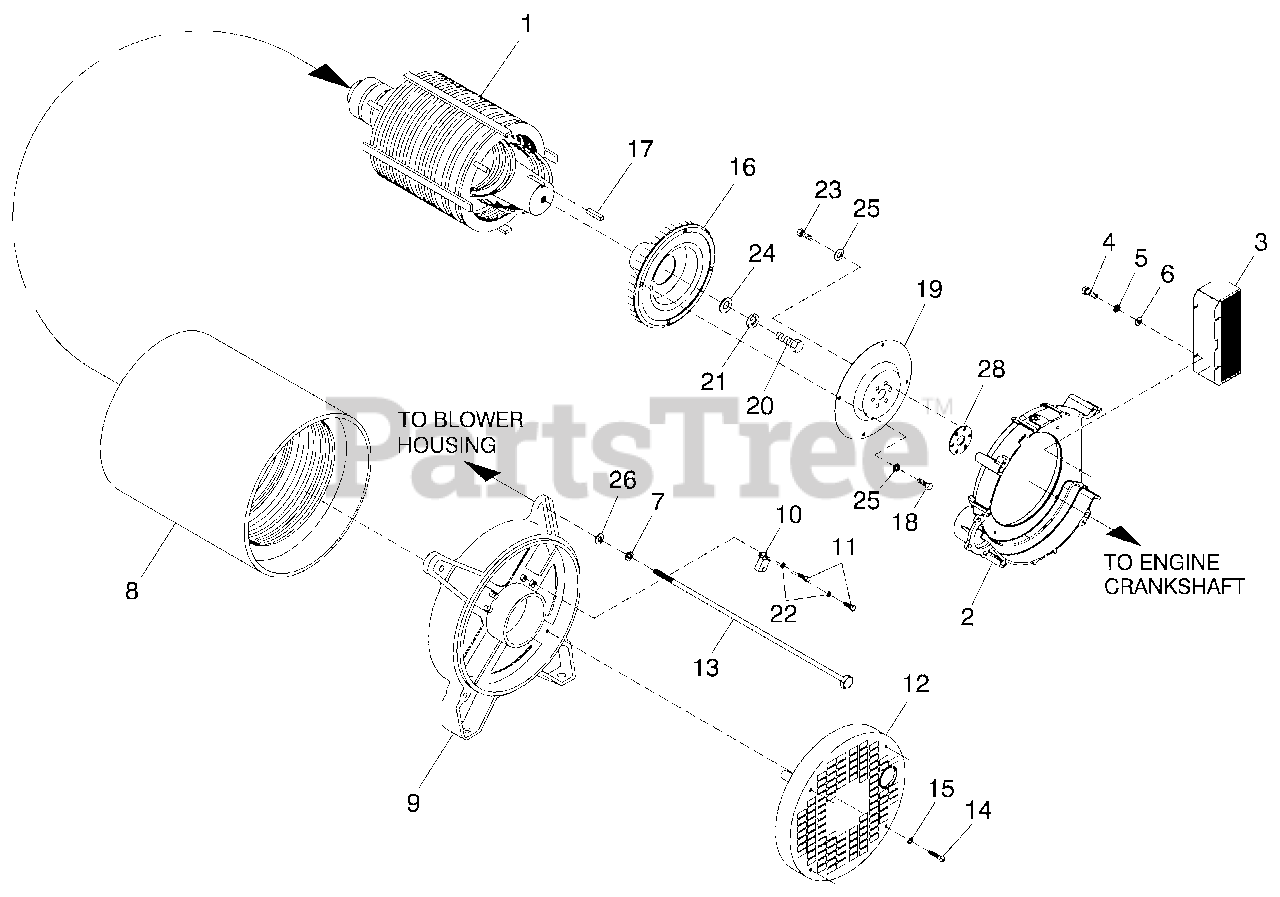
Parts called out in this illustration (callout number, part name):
1	ASSY RTR 104 KD1 HI EFF (18KW)
2	HOUSING BLOWER LG PILOT
3	BLOWER HOUSING SCREEN
4	SCREW PPHM M5-0.8 X 8 ZINC
5	WASHER LOCK M5
6	WASHER FLAT M5
7	WASHER LOCK M8-5/16
8	ASSY STR 104-18AD1 HI EFF (18KW)
9	BEARING CARRIER REAR LG PILOT
10	ASSY HOLDER BRUSH
11	SCREW HHC M4-0.7 X 16 G8.8
12	COVER REAR BEARING
13	BOLT STATOR X 16" LG (20KW & 25KW)
14	SCREW RHM #10-24 X 2
15	WASHER LOCK #10
16	FLYWHEEL & RINGGEAR ASSY 1.6L
17	KEY SQ 3/8 X 1 STEEL
18	SCREW HHC M10-1.5 X 25 G8.8
19	PLATE FLEX 1.6L R12.7
20	SCREW HHC M12-1.75 X 35 G8.8
21	WASHER LOCK M12
22	WASHER SHAKEPROOF INT #8
23	SCREW HHC M10-1.0 X 20 G10.9
24	SPACER ROTOR SHAFT
25	WASHER .41 ID .94 OD .12 THK
26	WASHER FLAT .34 ID X .75 OD
28	PLATE SPACER 14GA 1.6L (TO BE USED WITH ENGINE PLATE
